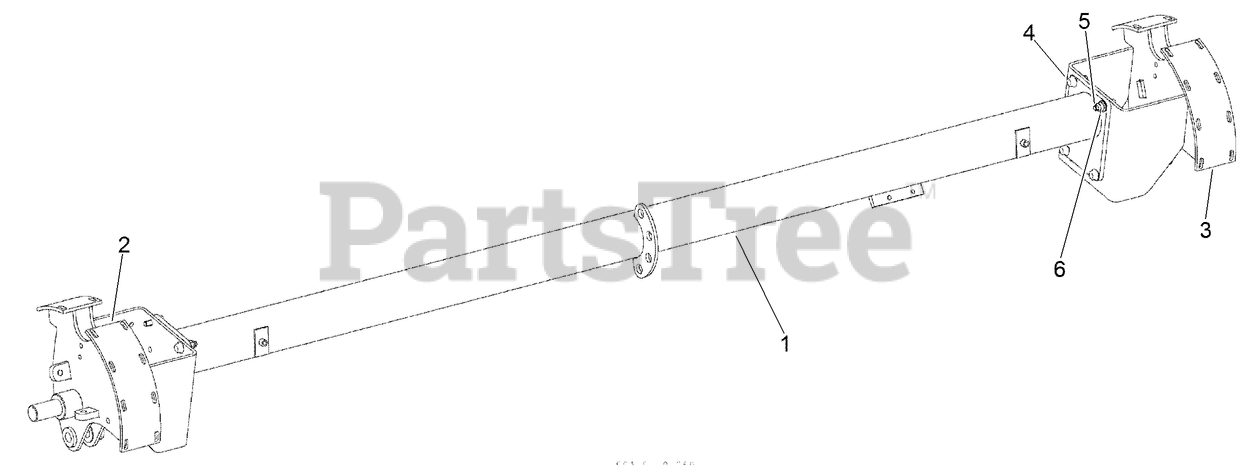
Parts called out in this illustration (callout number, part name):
1	ASSEMBLY - Rod Loader Spine
2	ASSEMBLY - Cam
3	ASSEMBLY - Cam
4	SCREW-HH
5	SCREW-HHF
6	NUT-FLANGE, NYLOCK
